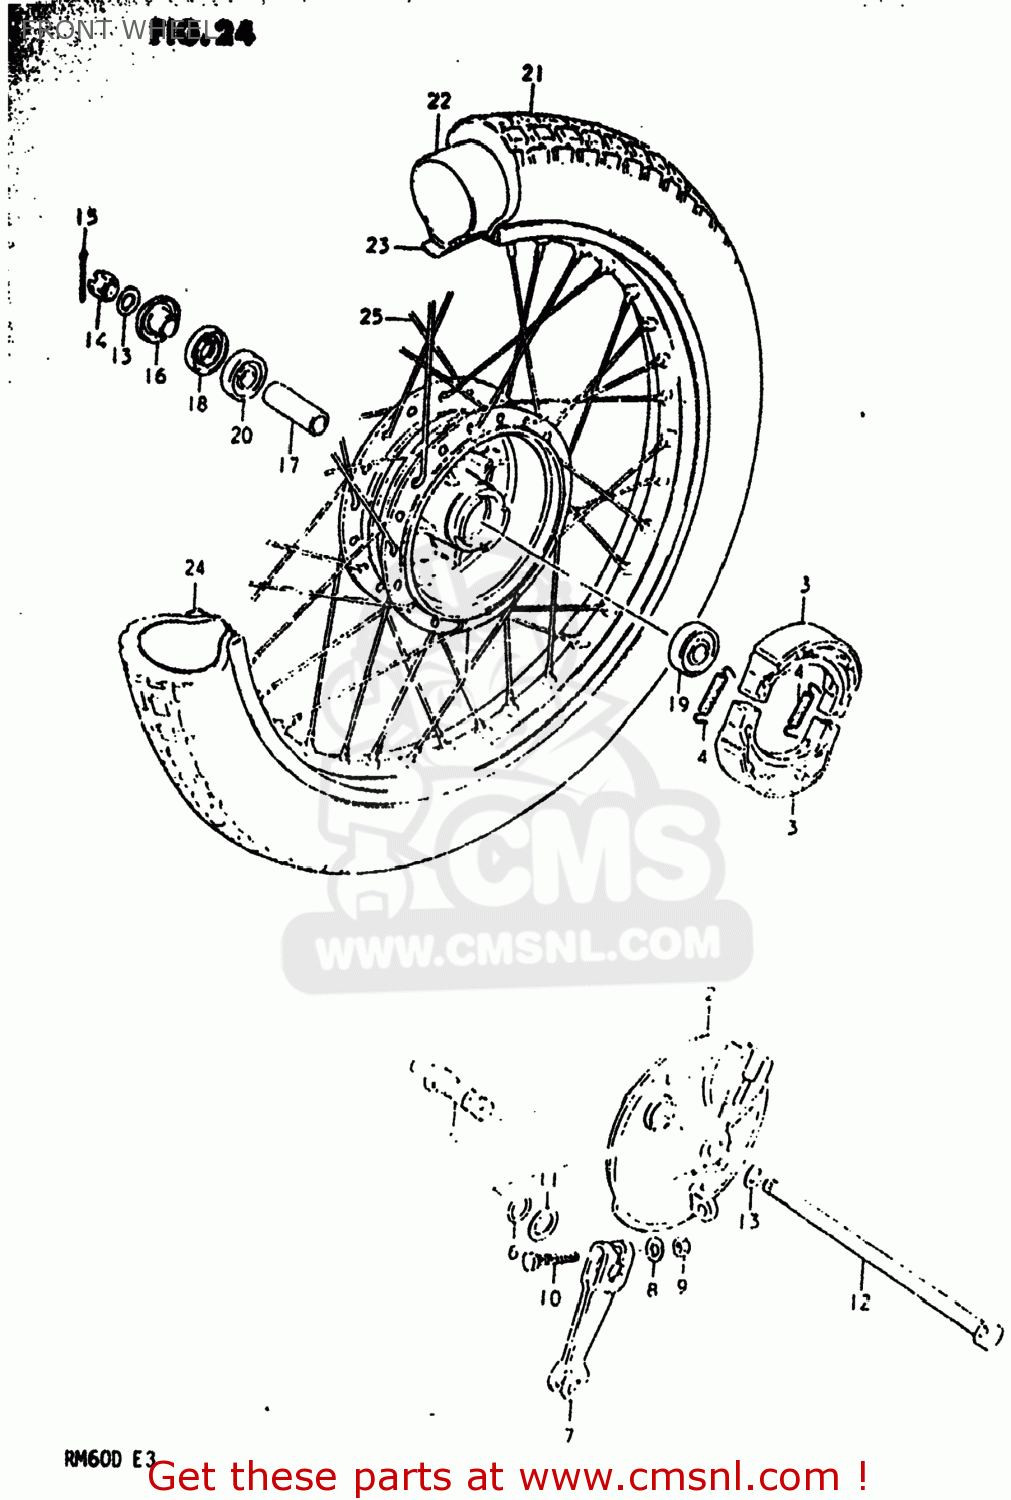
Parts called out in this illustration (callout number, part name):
1	HUB,FRONT
2	PANEL,FR BRAKE ANCHOR
3	SHOE,BRAKE
4	SPRING(L:34)
5	CAM,FRONT BRAKE
6	O-RING (D:2.4 ID:13.8)
7	LEVER,FR BRAKE CAM
8	WASHER
9	NUT
10	BOLT(6X33)
11	WASHER (14.5X22X1.6)
12	AXLE,FRONT
13	WASHER(10.5X22X2.3)
14	NUT
15	PIN 20X20
16	SPACER,FRONT AXLE,RIGHT
17	SPACER (10.2X16X51)
18	SEAL,OIL(15X31X5)
19	BEARING
20	BEARING
21	TIRE(2.25 14)
22	TUBE,INNER
23	PROTECTOR,INNER TUBE
24	RIM,FRONT WHEEL (1.40X14)
25	SPOKE SET,FRONT
